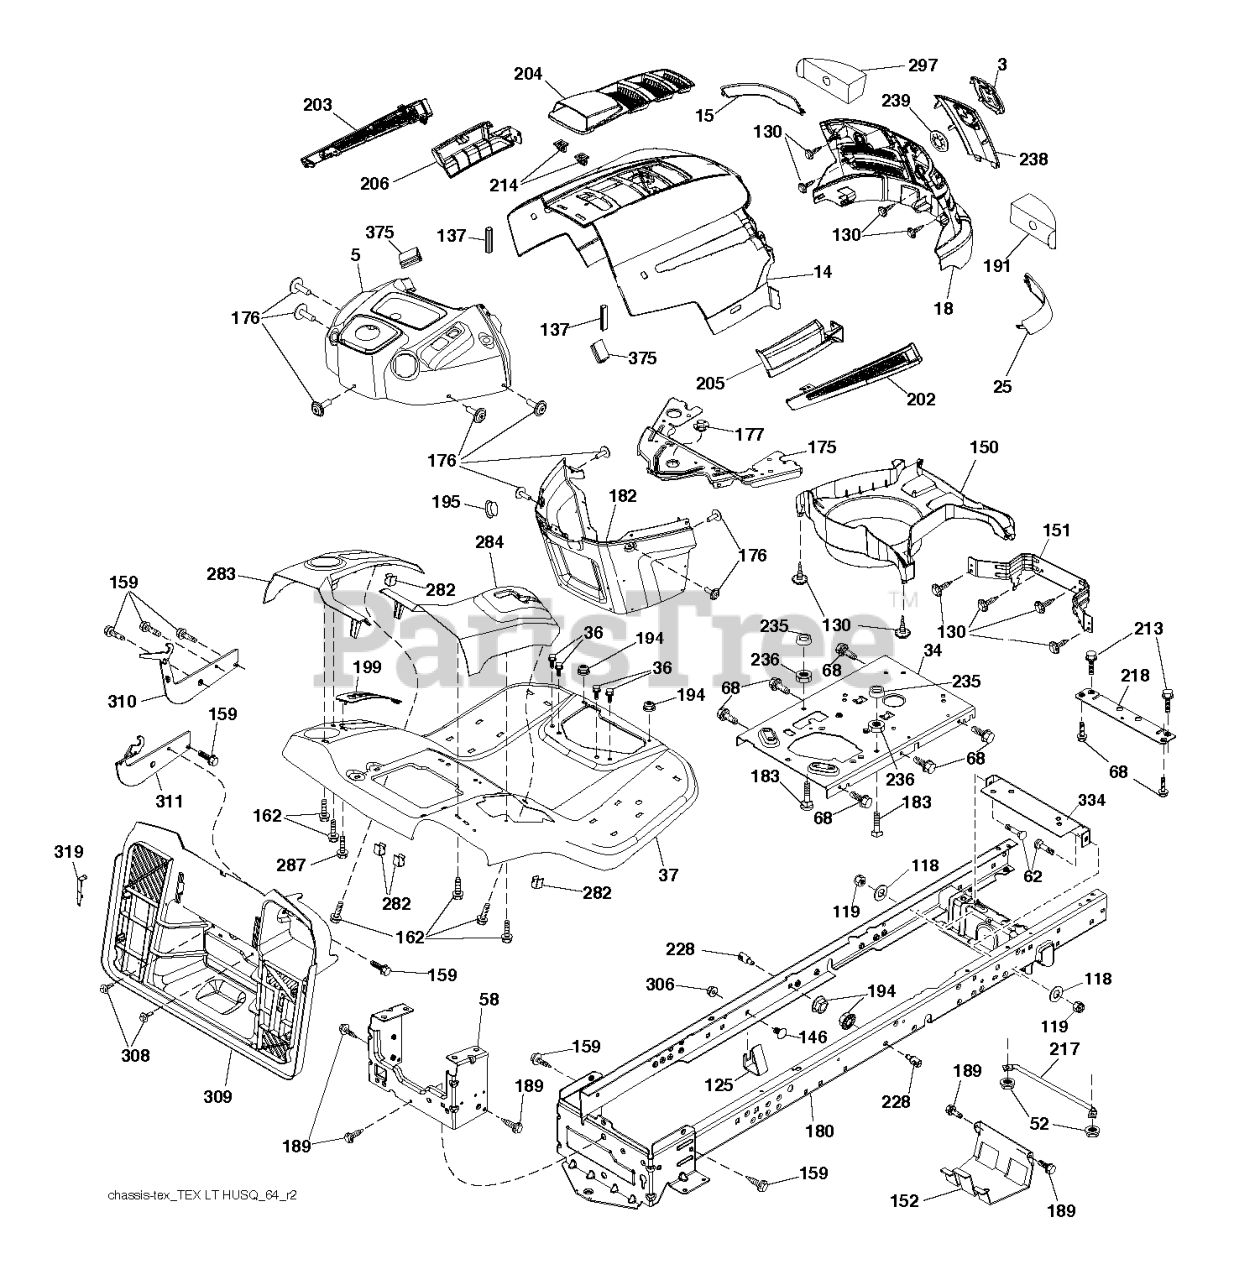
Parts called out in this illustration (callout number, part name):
3	LOGO.HUSQ.GT.LT.CROWN.H
5	SUBASM.DASH.UPPER.W/BUMPER
14	HOOD.HUSQVARNA.LT.ORANGE
15	LENS.HUSQVARNA LT.RH
18	GRILLE.SVC.HUSQVARNA.GREY
25	LENS.HUSQVARNA LT.RH
34	PLATE.ENGINE.10GA.CRD.GENII
36	SCREW 5/16"
37	FENDER.TEX.SRD.CRD.BASE
52	LOCKNUT
58	DRAWBAR UPPER 2PC SMALL FENDER
62	BOLT D
68	Screw 5/16-18 x 1/2 Hex, Self Tapping 5/16-18 x 1/2
118	WASHER
125	CLIP.FUEL.LINE
130	SCREW.#10 X 0.750.BOS
137	BUMPER DASH
146	BOLT.RDHD.SHT.SQNK.3/8-16X5/8
151	BRACKET PIVOT
152	SHIELD.BROWNING.W/TEX
159	SCREW, 3/8-16X3/4
162	SCREW.HI-LO.CONSOLE
175	CROSSMEMBER
176	SCREW.#10-24X5/8.RN.QU
177	BUSHING STEERING
180	CHASSIS.WLDMNT.14GA.2PC.18".TI
182	DASH.LOWER.PREDATOR LT
183	BOLT.5/16-18X1-1/4 FULL THD
189	SCREW
191	INSERT.REFLECTIVE.RH.
194	NUT LOCK HEX FLANGE 5/16-18
195	PLUG.TEX.DASH.SVC.MINDER.GREY
199	PLATE DECK LIFT
202	VENT.SIDE.HUSQVARNA.LT.RT
203	VENT.SIDE.HUSQVARNA.LT.LFT
204	SUBASM.TOP.VENT.HUSQ.LT
205	SKIRT.SIDE.HUSQVARNA.LT.RT
206	SKIRT.SIDE.HUSQVARNA.LT.LEFT
213	BOLT
214	CLIP.RETAINER.TINNER.
217	ROD.PIVOT.HOOD
218	X-PIECE.HOOD.STOP.NON/
228	STUD.FASTNER.W/ANTI-ROTATE
235	SPACER FENDER
236	NUT.CENTERLOCK.5/16-
238	TRIM.HUSQ LT.668
282	CLIP.RETAINER.CONSOLE.LT.HUSQ
283	CONSL.DECKLIFT.LH.SRD.TEX.CRD
284	CONSL.SHIFT.GEAR.RH.SRD.GREY
287	SCREW 1/4X20
297	INSERT REFLECTIVE
306	NUT LOCK FLG 3/8-16 UNC
308	BOLT.5/16-18UNCX3/4 W/SEMS.BLK
309	BACKPLATE.BAGGER.V2.SRD
310	LH.ADJUST.HANGER.BRACKET.ASM
311	RH.ADJUST.HANGER.BRACKET.ASM
319	BRACKET.ACTUATOR.BAGGER.SRD
334	BRACKET.ENGINE
375	BUMPER CLIP-ON. DASH 1"
